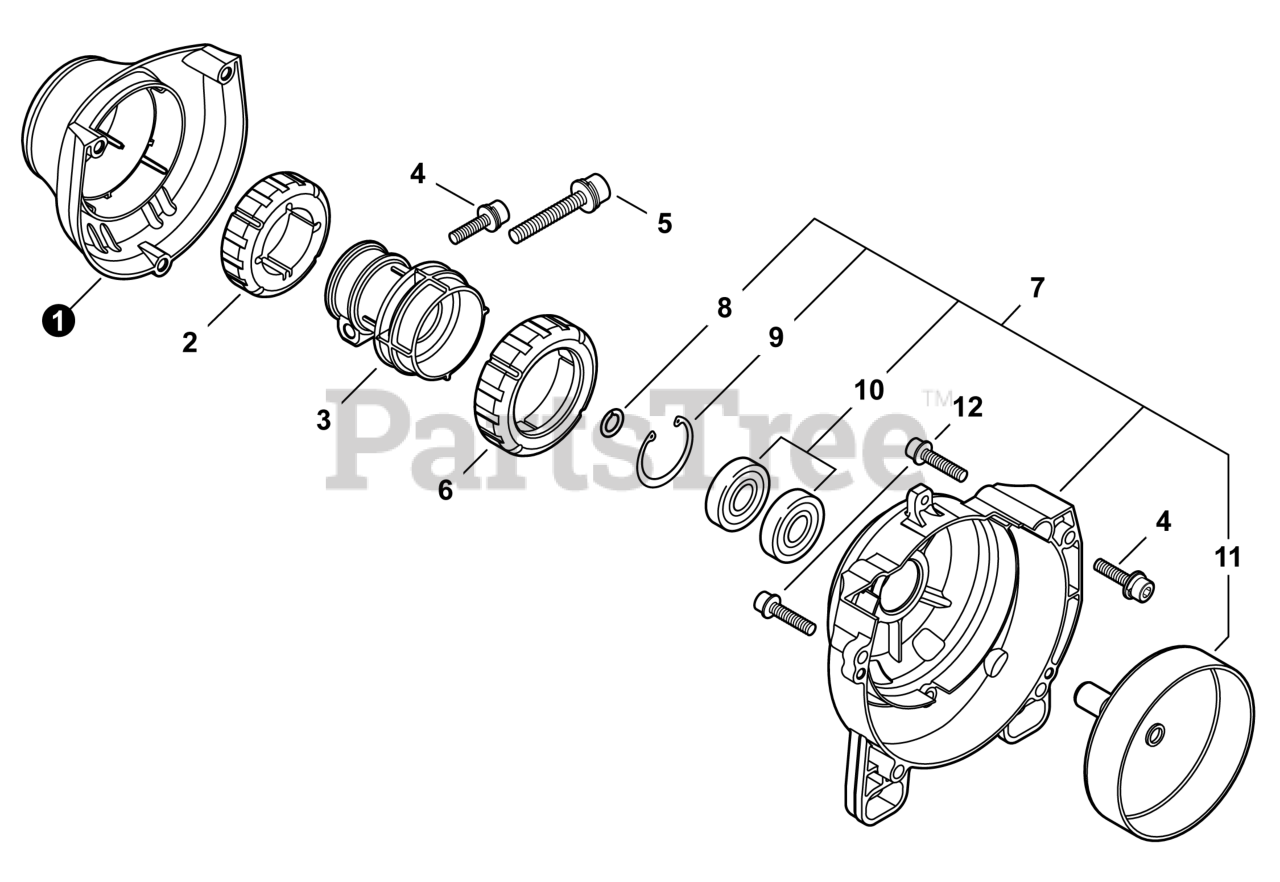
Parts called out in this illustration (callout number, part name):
1	COVER, CUSHION
2	HOLDER, FRONT CUSHION
3	CUSHION
4	BOLT 5×16
5	BOLT M6×28
6	HOLDER, REAR CUSHION
7	COVER ASSY, FAN
8	RING, SNAP 12
9	RING, SNAP 28
10	BEARING, BALL 6001 DDU C3
11	DRUM, CLUTCH
12	BOLT 5×20
